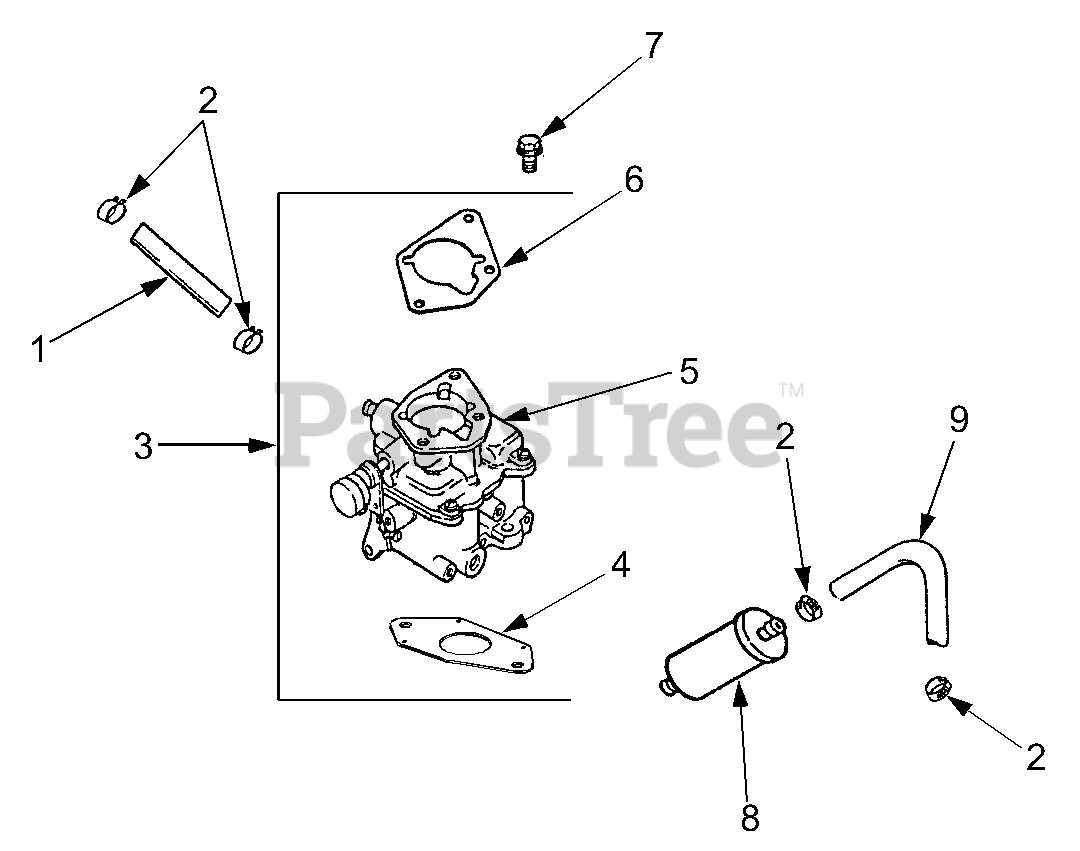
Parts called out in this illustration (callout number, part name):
1	Line, Fuel 10"
2	Clamp, Hose
3	Kit, Carburetor w/Gasket
4	Gasket, Carburetor
5	Carburetor Assembly
6	Gasket, Air Cleaner Base
7	Screw, Hex Flange, M6 x 1.0 x
8	Filter, Fuel
9	Line, Fuel 11"
